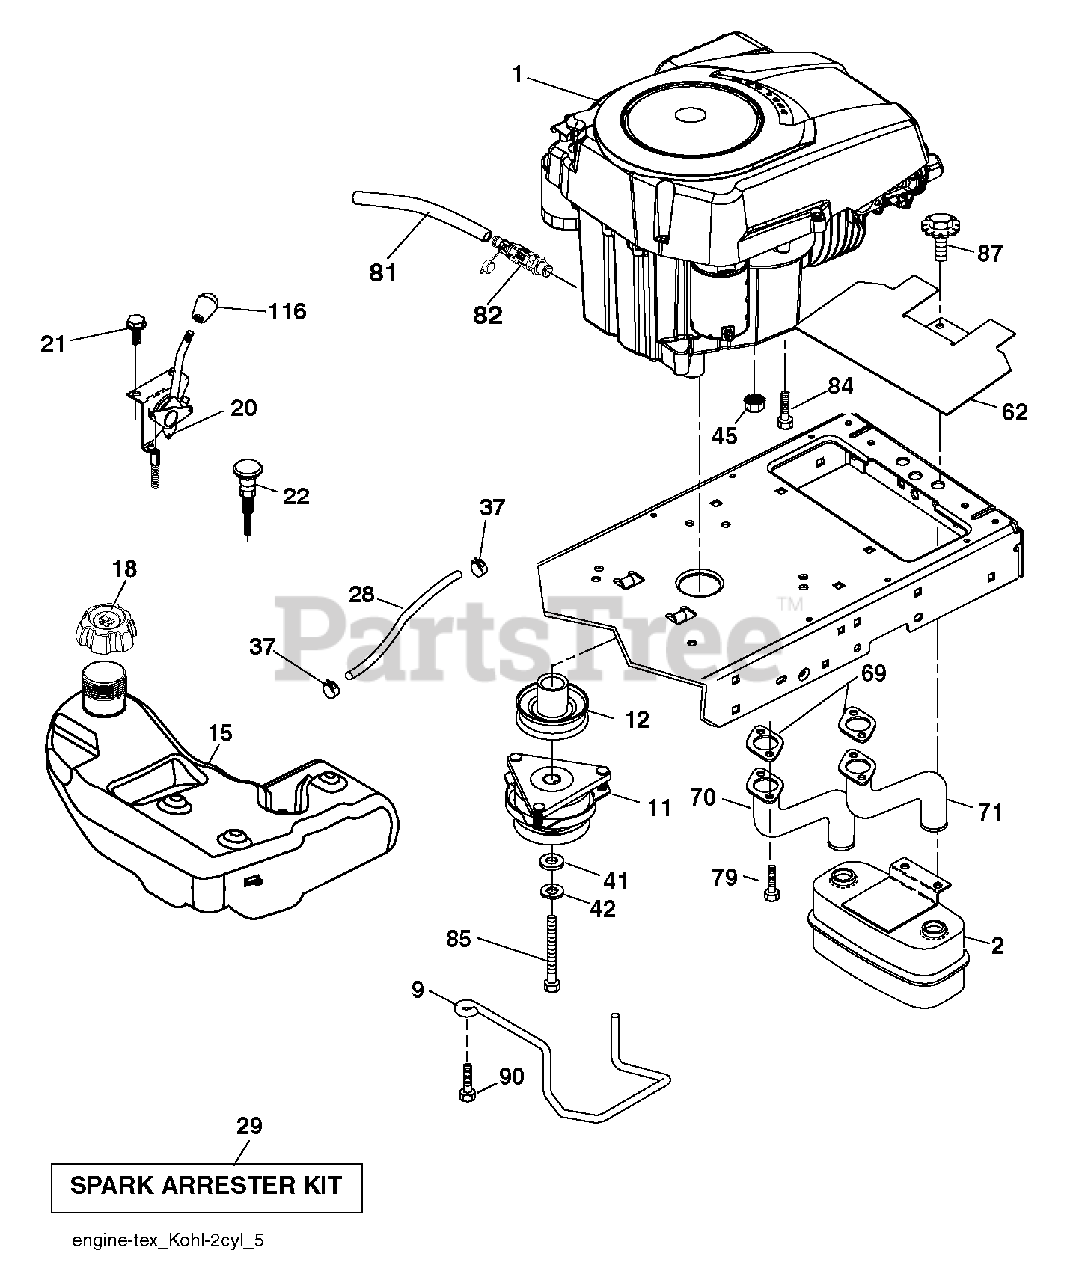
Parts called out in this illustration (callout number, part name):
2	MUFFLER ASSM
9	KEEPER.BELT.ENGINE.4.2
12	PULLEY.ENGINE.TUFFTORQ
15	TANK.ASSY.3.GAL.EPA
18	CAP ASM.FL.RTCHT.3"GRY.E10
20	CONTROL.THROT.PRO
21	SCREW.#10 X 0.750.BOS THREAD
22	CONTROL CHOKE
28	LINE.FUEL.64"REAR.EMIS
29	ARRESTER SPARK (OPTIONAL)
37	HOSE CLAMP
42	LOCKWASHER
62	SHIELD.HEAT.MUFFLER
70	PIPE-EXHAUST LH
71	PIPE-EXHAUST RH
79	SCREW.SOCKET HD.5/16-1
81	TUBE, DRAIN OIL ASM.
82	VALUE.OIL.DRAIN
84	SCREW 3/8-16X1
87	BOLT.5/16-18UNCX1.W/SE
90	SCREW 3/8-16X1
116	KNOB - SHIFT
